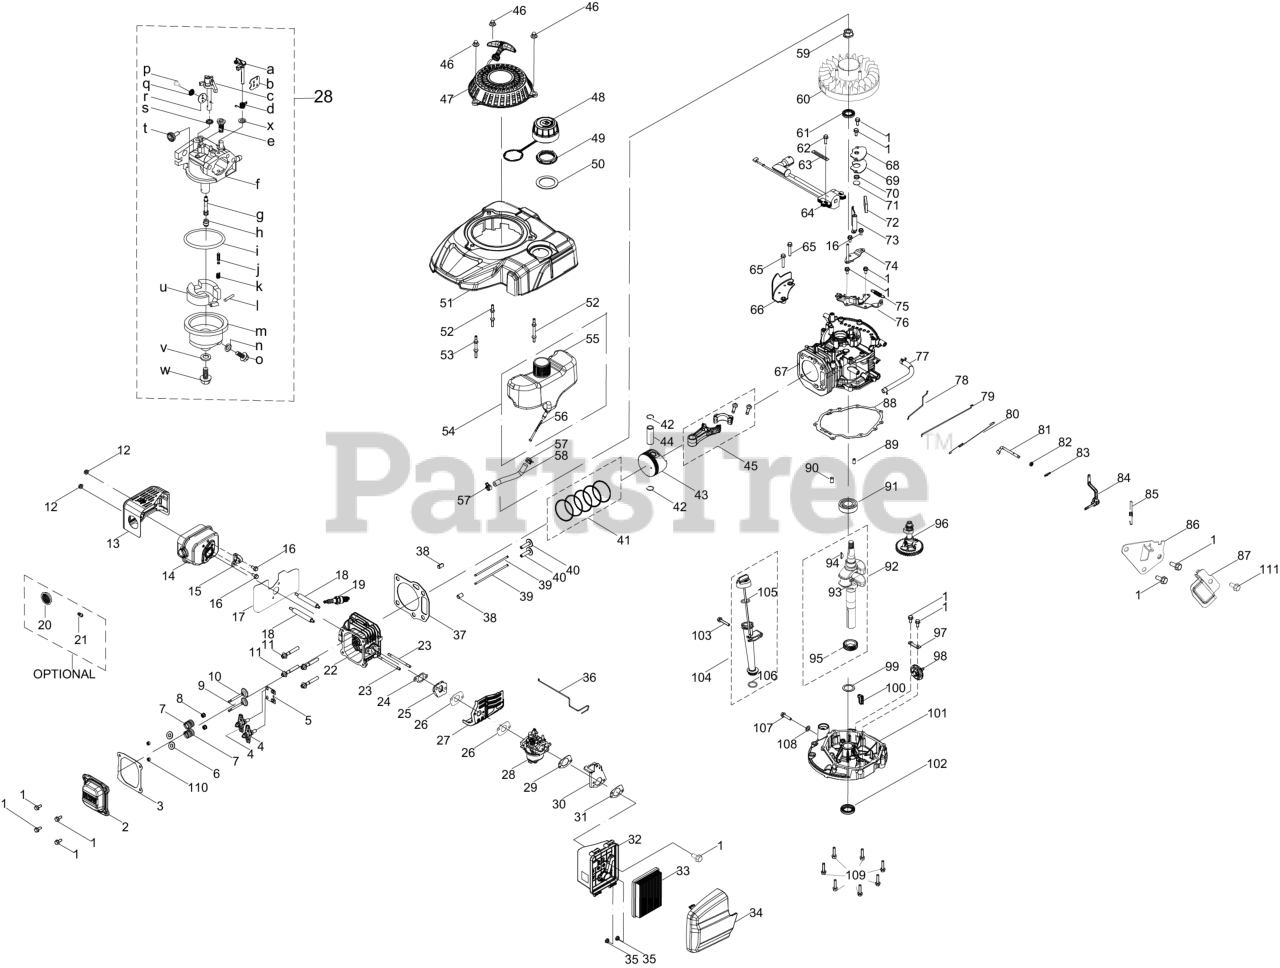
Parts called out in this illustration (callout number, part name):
1	BOLT M6-1 x 14 GR8.8
2	VALVE COVER
3	VALVE COVER GASKET
5	ROCKER ARM BASE
6	VALVE SPRING SEAT
7	VALVE SPRING
8	INTAKE VALVE SEAL
9	EXHAUST VALVE
10	INTAKE VALVE
11	BOLT-M8 x 54
12	NUT HEX M6-1
13	MUFFLER SHIELD
14	MUFFLER ASSEMBLY
15	CHOKE TEMP CONTROL THERMOSTAT
16	BOLT M6-1 x 12 GR8.8
17	MUFFLER GASKET
18	STUD M6-1 x 95
19	SPARK PLUG (F5RTC/RN11YC4/BPR5ES)
20	SPARK ARRESTOR
21	SCREW M3.5 x 9.5
22	CYLINDER HEAD
23	STUD M6 x 90
24	CARBURETOR INSULATOR GASKET
25	CARBURETOR INSULATOR
26	CARBURETOR GASKET
27	CARB HEAT SHEILD
28	CARBURETOR
29	AIR FILTER BRACKET GASKET
30	AIR FILTER BRACKET
31	AIR FILTER BASE GASKET
32	AIR FILTER BASE
33	AIR FILTER
34	AIR FILTER COVER
36	CHOKE TEMP CONTROL LINKAGE
37	HEAD GASKET
38	PIN (10MMx16MM)
41	PISTON RING SET
42	WRIST PIN CLIP
45	CONNECTING ROD
46	ACORN NUT M6-1
47	RECOIL STARTER ASSEMBLY
48	FUEL CAP W/TETHER
49	FUEL TANK NUT
50	FUEL TANK GROMMET
51	ENGINE SHROUD W/O IGNITION SWITCH
52	STARTER/SHROUD REAR STUD
53	STARTER/SHROUD FRONT STUD
54	Fuel Tank Assembly
56	FUEL FILTER
57	CARBURETOR HOSE CLAMP
59	FLYWHEEL NUT M14-1.5
61	UPPER CRANKSHAFT SEAL
62	BOLT M6-1 x 20 GR8.8
63	FLEXIBLE CLAMP
64	IGNITION COIL ASSEMBLY
65	BOLT M6-1 x 25 GR8.8
66	ENGINE BRAKE COVER PLATE
68	BREATHER COVER PLATE
69	BREATHER GASKET
70	BREATHER VALVE SPRING
71	BREATHER VALVE
72	BREATHER SCREEN
74	AIR VANE BRACKET
75	ENGINE BRAKE SPRING
76	ENGINE BRAKE ASSEMBLY
77	BREATHER HOSE ASSEMBLY
78	CHOKE LINKAGE
79	THROTTLE LINKAGE
80	THROTTLE LINKAGE SPRING
81	GOVERNOR ARM SHAFT
84	GOVERNOR ARM ASSEMBLY
85	GOVERNOR SPRING
86	COMPONENT BRACKET
87	GOVERNOR SHIELD
88	CRANKCASE COVER GASKET
89	DOWEL PIN 7 X 14
90	DOWEL PIN 9 X 14
92	CRANKSHAFT
93	CRANKSHAFT
94	WOODRUFF KEY
95	TIMING GEAR
96	CAMSHAFT ASSEMBLY
97	GOVERNOR GEAR MOUNTING PLATE
98	GOVERNOR GEAR
99	THRUST WASHER
100	OIL RETURN SEAL
101	CRANKCASE COVER
102	LOWER CRANKSHAFT SEAL
103	BOLT M6-1 x 35 GR8.8
104	DIPSTICK ASSEMBLY
107	OIL DRAIN PLUG
108	FLAT WASHER
109	BOLT-M6-1 x 28 GR8.8
111	BOLT M6-1 x 10 GR8.8
S	Throttle/Choke Shaft Fiber O-Ring
